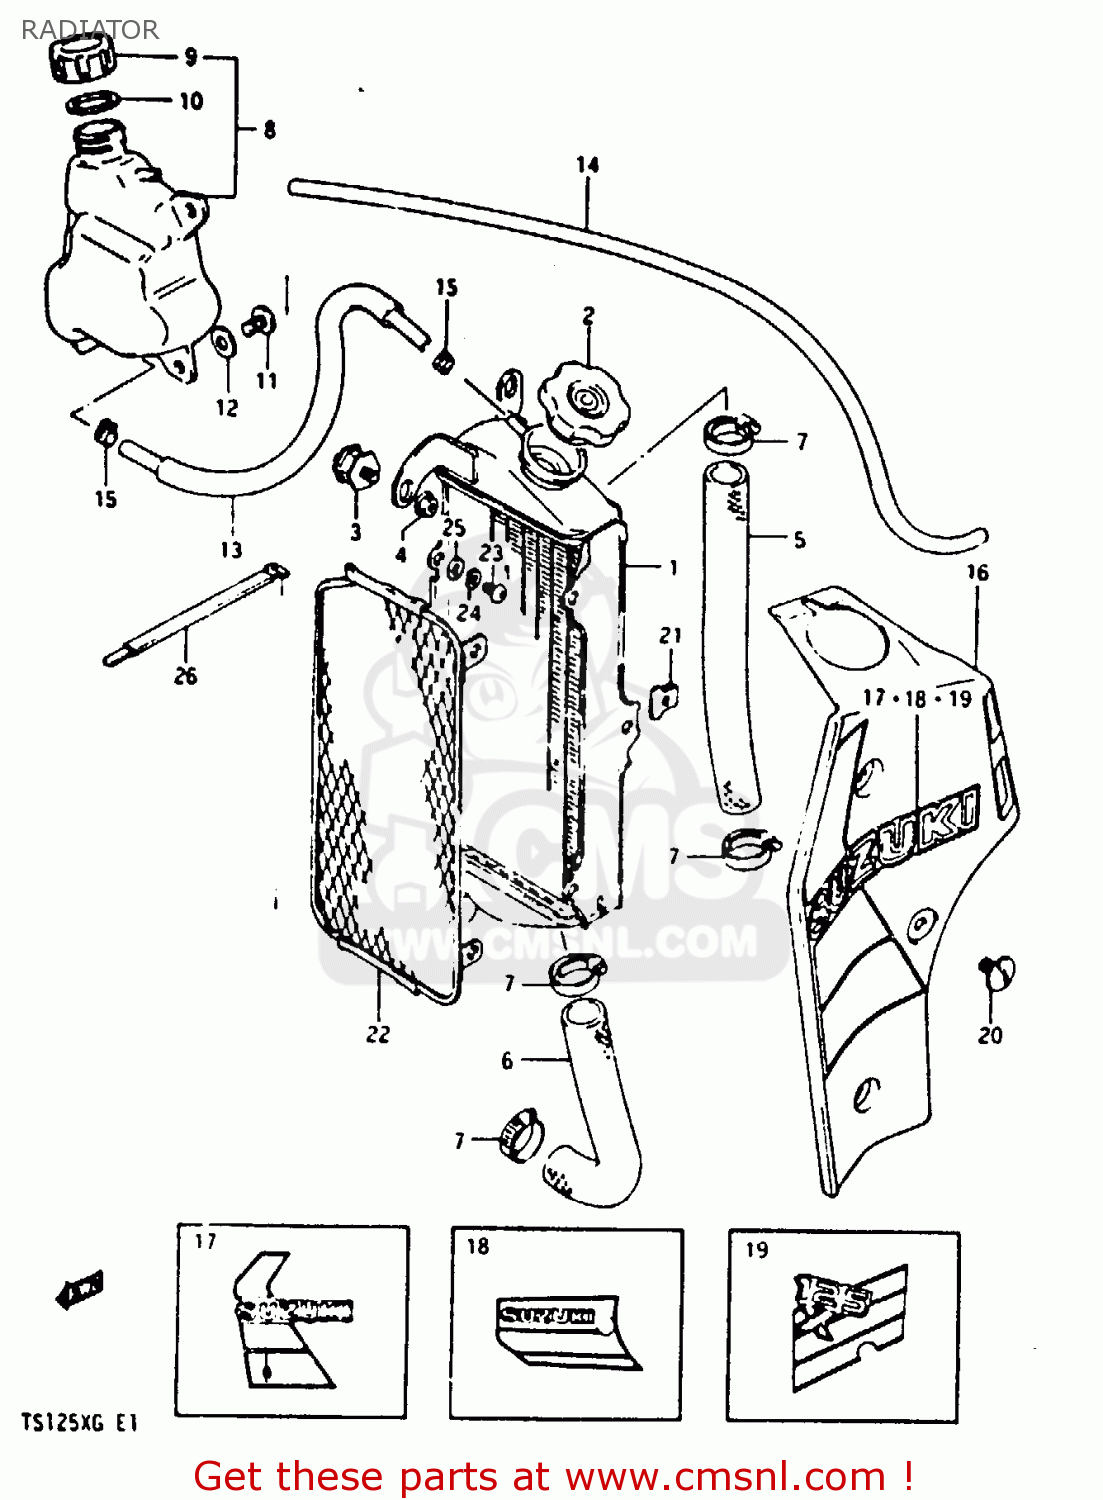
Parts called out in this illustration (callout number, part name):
1	RADIATOR
2	CAP,RADIATOR
3	BOLT,RADIATOR CUSHION
4	NUT 6MM
5	HOSE,RADIATOR INLET
6	HOSE, OUTLET
7	CLAMP
8	TANK ASSY, RESERVE
9	CAP,RESERVOIR TANK
10	GASKET,RESERVOIR TANK CAP (NAS)
11	SCREW
12	WASHER (6.5X18X1.6)
13	HOSE, RESERVE TANK INLET
14	HOSE
15	CLIP
16	COVER, RADIATOR (RED)
17	TAPE SET
18	TAPE SET
19	TAPE SET
20	SCREW(6X14)
21	PLATE,RADIATOR COVER FITING
22	BUMPER, RADIATOR
23	SCREW
24	WASHER,LOCK
25	WASHER
26	CLAMP
